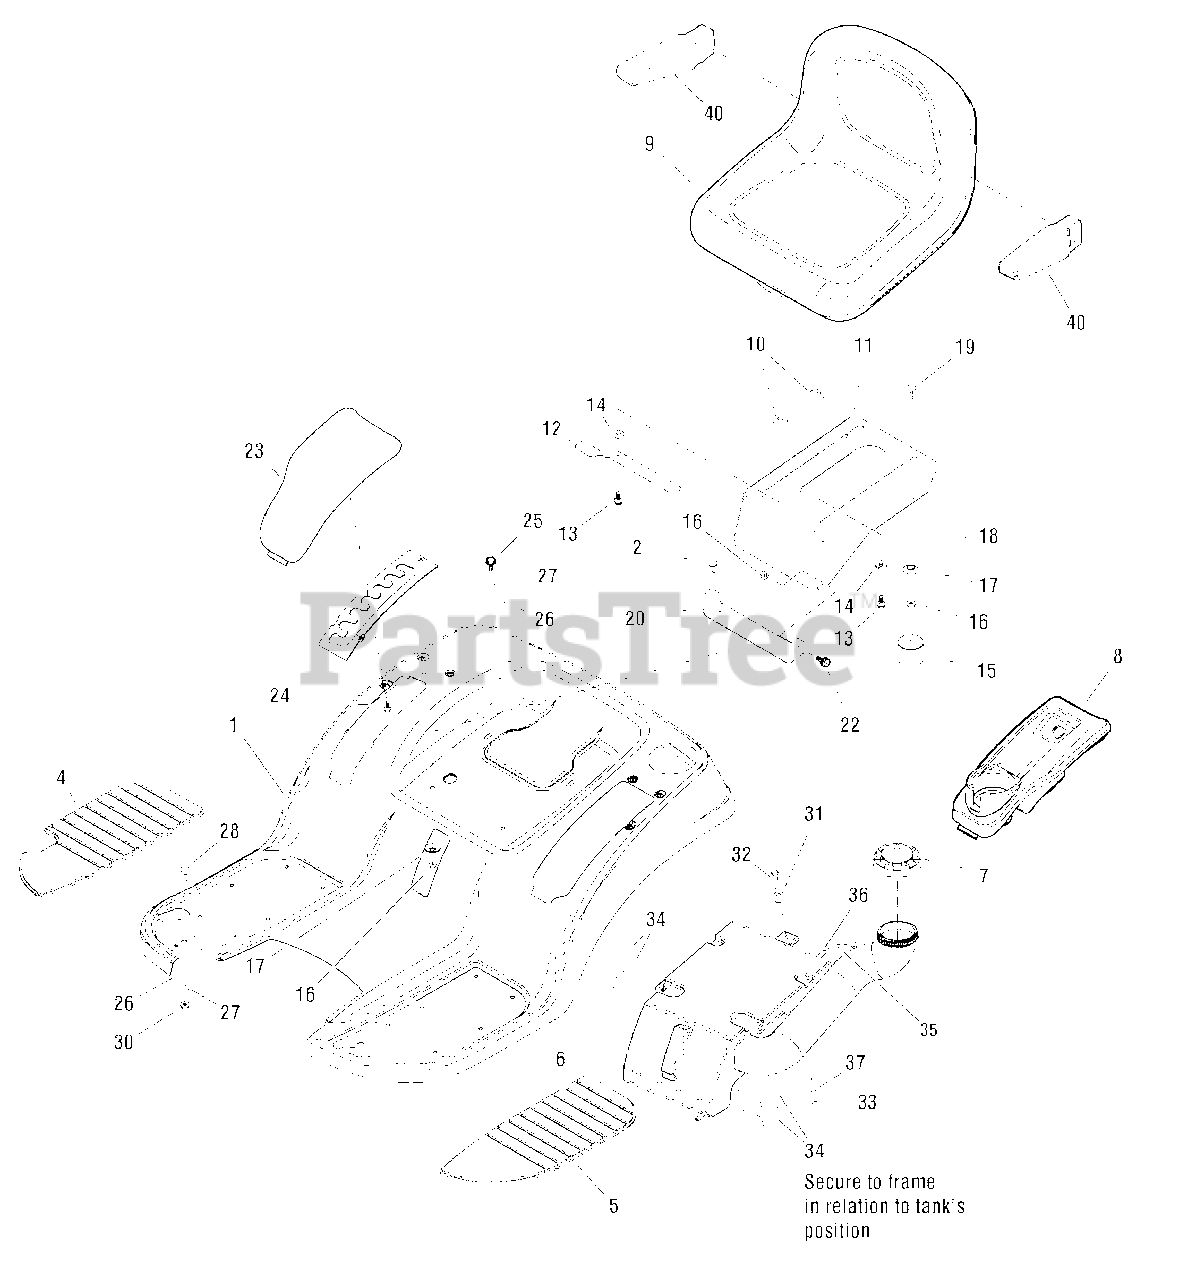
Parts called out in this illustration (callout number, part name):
1	DECK, Seat With Foot Rests
2	BOLT, 5/16-18 x 3/4
4	PAD, Footrest, Right
5	PAD, Footrest, Left
6	TANK, Fuel 9-2770-244
7	CAP, Fuel
8	POD, Cup Holder, Left
9	SEAT, High Back
9	SEAT, High Back, With Arm Rest Mount
10	SPACER
11	SUPPORT, Seat
12	LATCH, Seat
13	SCREW, Flange 5/16-18 x 1
14	WASHER, 5/16
15	COVER, Spring
16	NUT, Hex Flange, 5/16-18
17	WASHER, Spring
18	SPRING, Compression
19	BOLT, Carriage, 5/16-18 x 3/4
20	PIVOT, Seat
22	BOLT, Shoulder, 5/16-18 x 1/8
23	POD, Lift, Right
24	SCREW, Hex, 1/4-1/2
25	BOLT, M8 x 16
26	WASHER, 8.4
27	WASHER, 8
28	BOLT, M8 x 20
30	NUT, M8
31	DISTANCE, Lift 0-9521-289
32	BOLT, M6 x 30
33	NUT, M6
34	BRAID, Steel Insert 0-9634-219
35	HOSE, Air Escape 1-9920-248
36	CLIP, UM 5008
37	WASHER, 6.6
40	KIT, Arm Rest
